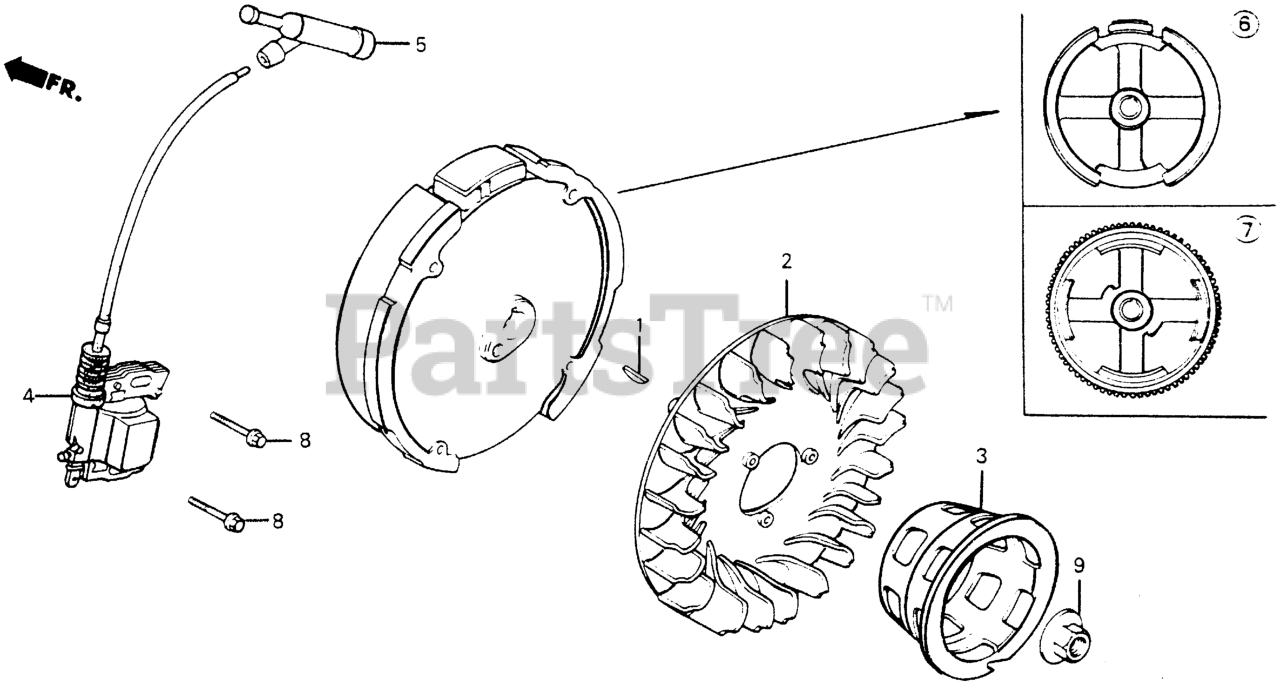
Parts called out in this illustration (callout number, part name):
1	KEY, SPECIAL WOODRUFF (25X18)
2	FAN, COOLING
3	PULLEY, STARTER
4	COIL ASSY., IGNITION Use up to Engine SN 1530314.
5	CAP ASSY., NOISE SUPPRESSOR (Honda Code 3526837). (NICHIWA Y-EZ RTFM256)
6	FLYWHEEL
8	BOLT, FLANGE (6X28) (CT200) Use up to Engine SN 1530314.
8	BOLT, FLANGE (6X25) Use up to Engine SN 2056819.
9	NUT, SPECIAL (14MM)
